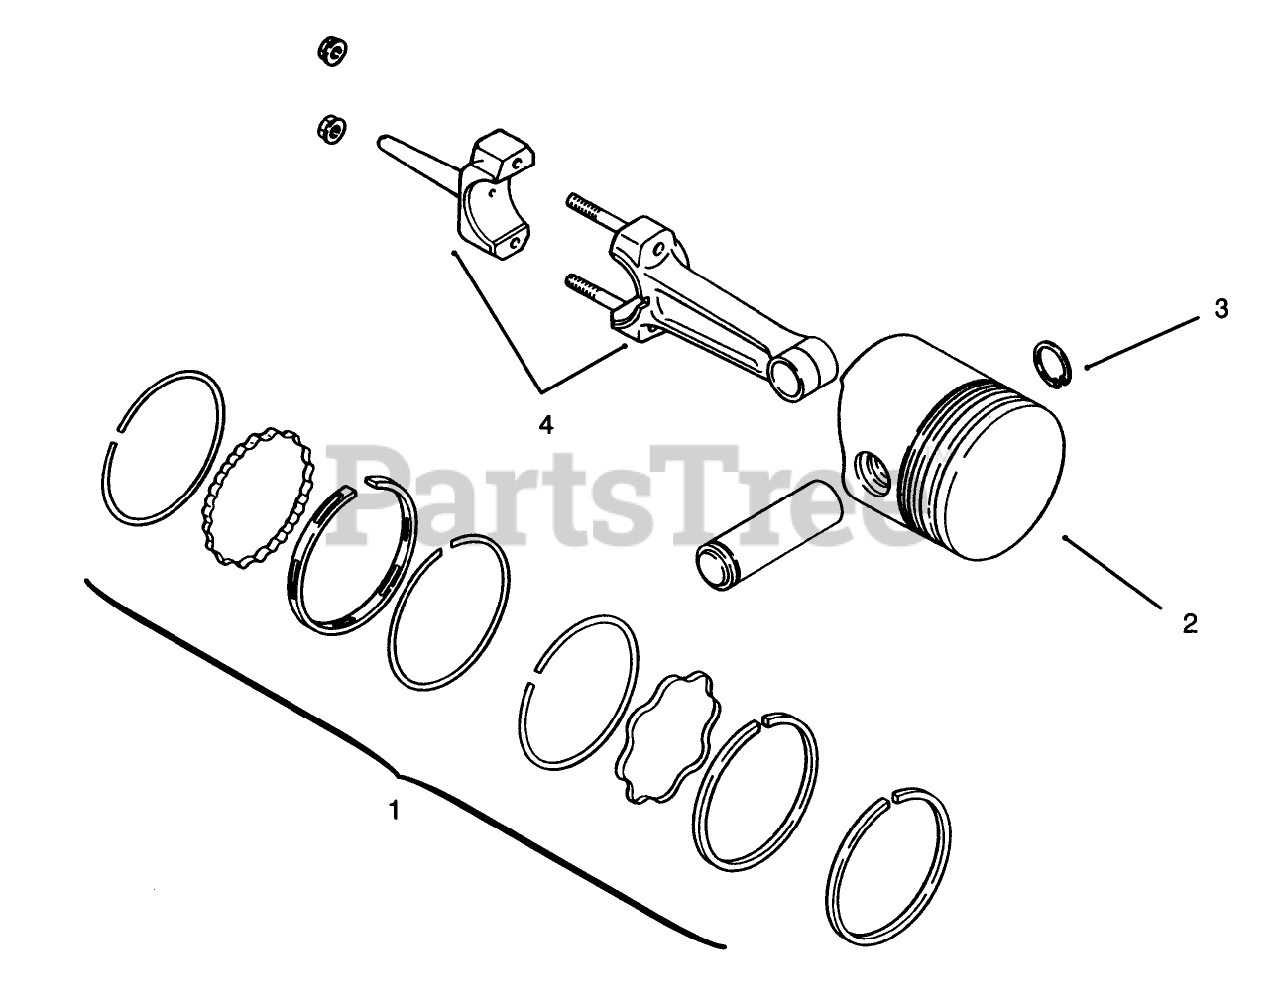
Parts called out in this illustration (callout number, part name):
1	KOHLER 47-108-01
2	KOHLER 47-874-16
3	KOHLER 47-018-01
4	KOHLER 45-067-24
